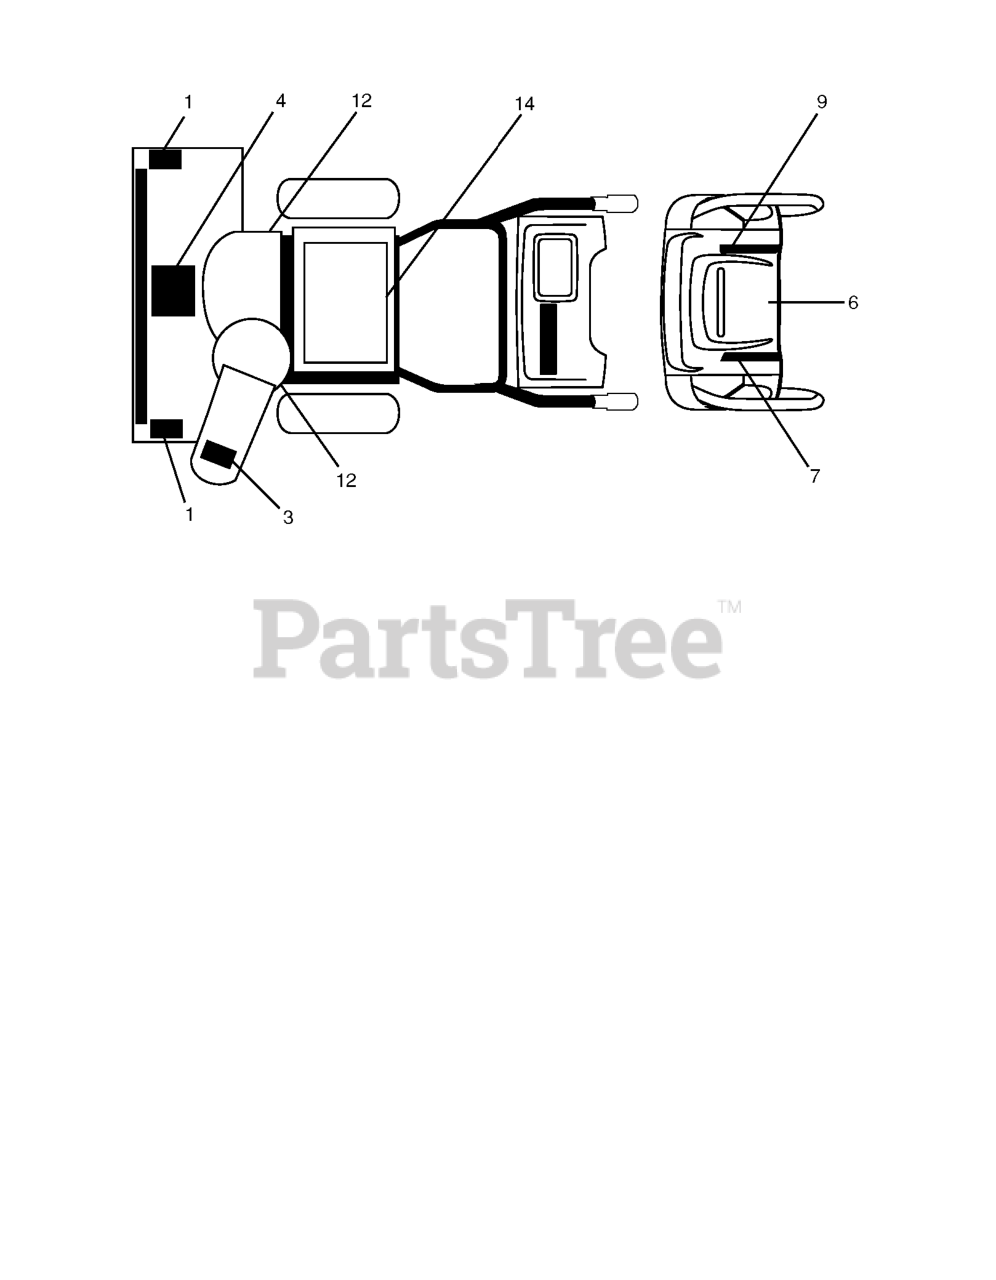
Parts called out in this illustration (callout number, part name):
1	DECAL.AUGER.SAFETY.
3	DECAL.CHUTE.SAFETY.
4	DECAL.AUGER."
7	DECAL.CONS.LT.WO/DEFL.GRY
9	DECAL.CONS.RT.SPD/LEV/PWRST.
12	DECAL.BELT.GUARD.
14	DECAL.FENDER
